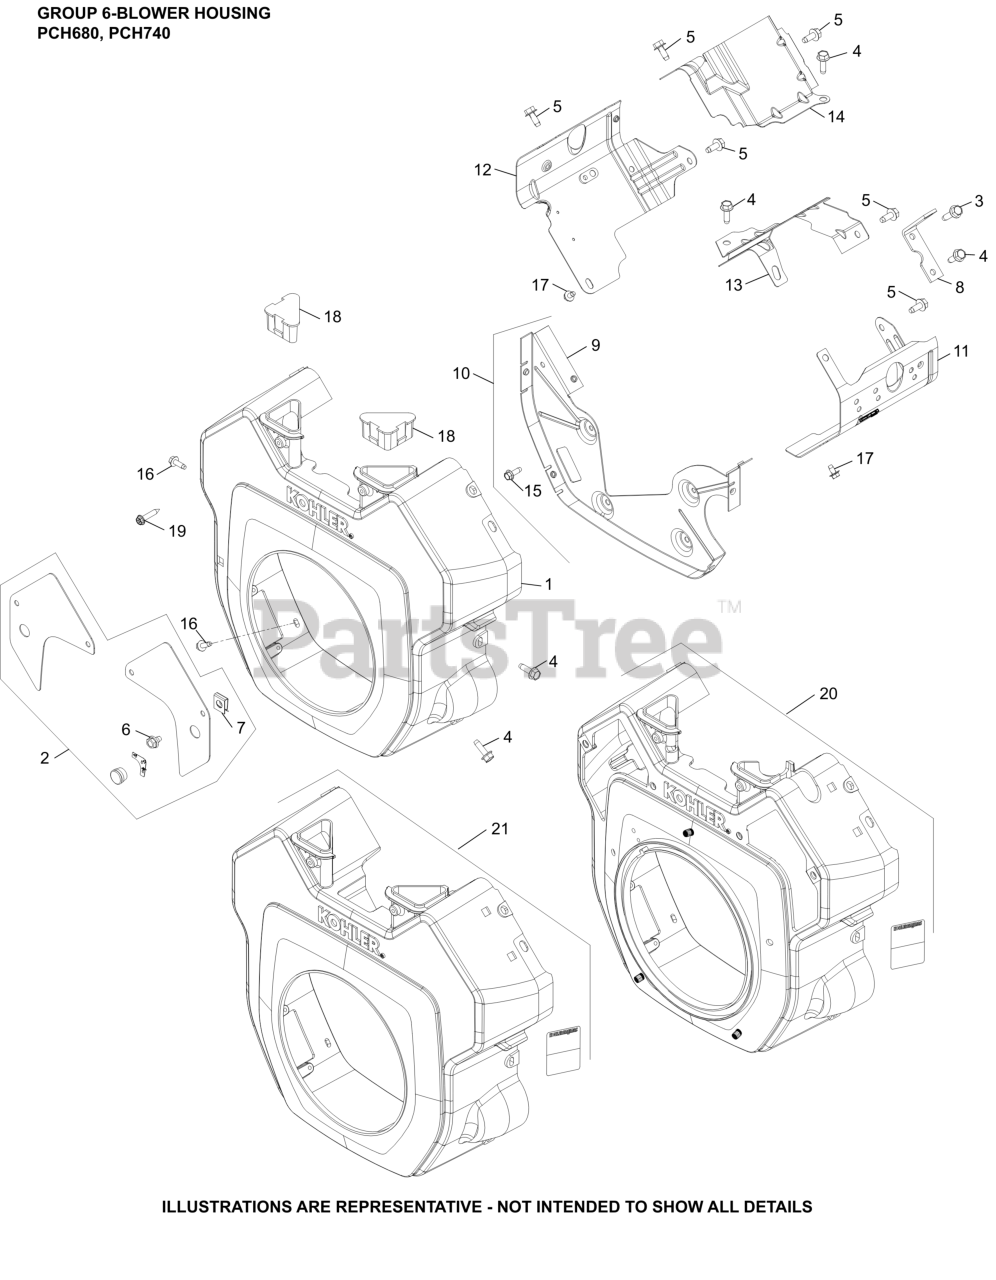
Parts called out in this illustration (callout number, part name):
1	KIT, BLOWER HOUSING
1	HOUSING, BLOWER
5	SCREW, THREAD FORMING
8	STRAP, LIFT
9	PLATE, BACKING
10	KIT, BACKING PLATE
11	KIT, RIGHT BARREL
12	BAFFLE LEFT BARREL
13	BAFFLE, VALLEY #1 CYLINDER
14	BAFFLE, VALLEY #2 CYLINDER
15	SCREW, THREAD FORMING
16	SCREW, THREAD FORMING
17	SCREW, THREAD FORMING
18	COVER, BLOWER HOUSING
